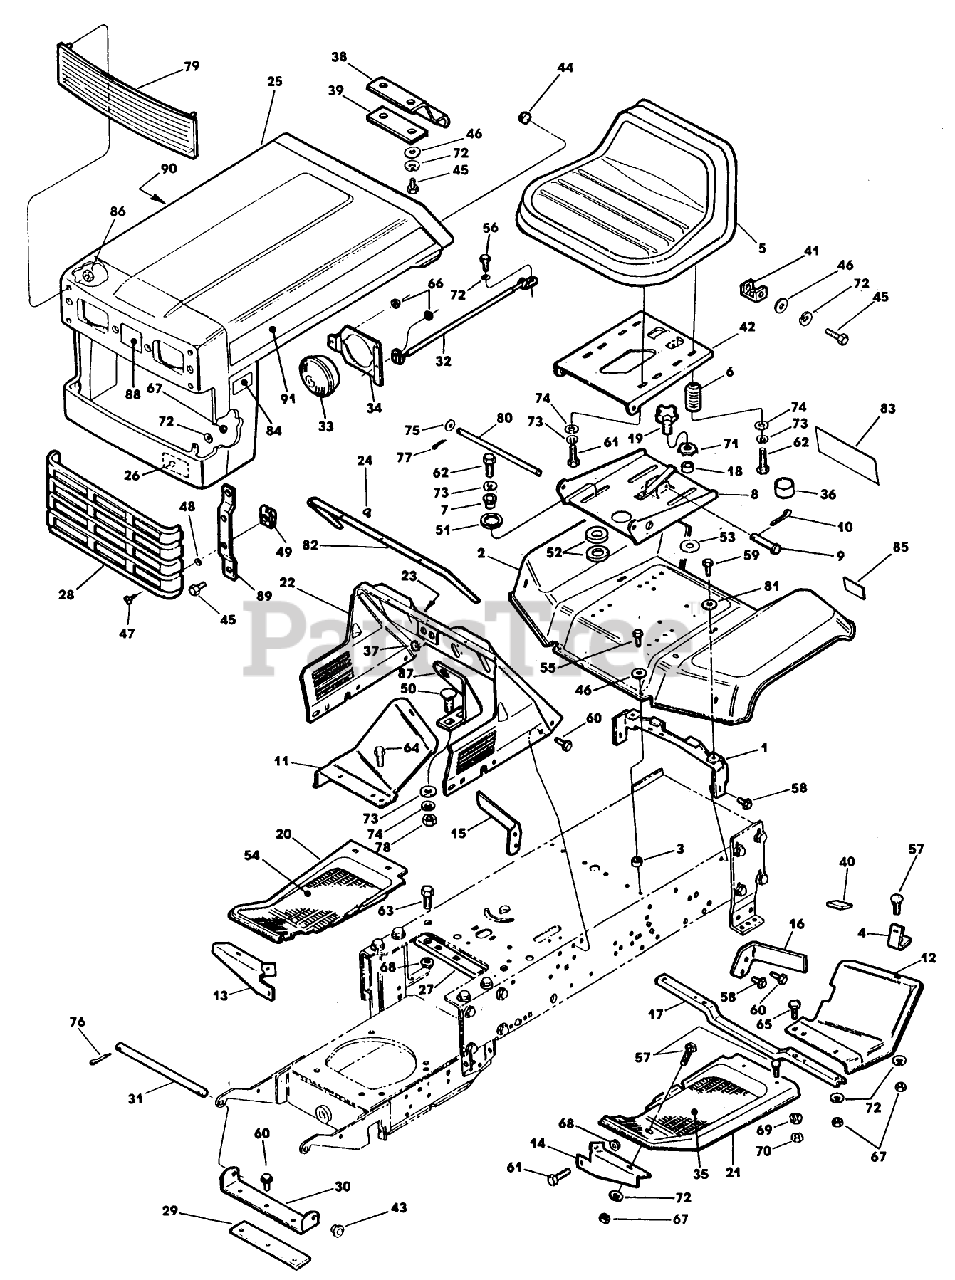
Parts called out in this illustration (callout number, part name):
1	BRACKET-SEAT SUPT
8	Support, Seat Slide
25	Hood Assembly (11 H.P. Only)
28	INSERT - GRILLE
36	CAP-PROTECTOR
42	PIVOT AY - SEAT *B
43	BEARING-NYLINER
45	SCREW-HH
47	FASTENER-1/4 TURN
52	WASHER-PLASTIC
59	SCREW-HWH
61	SCREW - HEX
69	NUT-LOCKING
85	REFLECTOR
91	DECAL - HOOD LH
